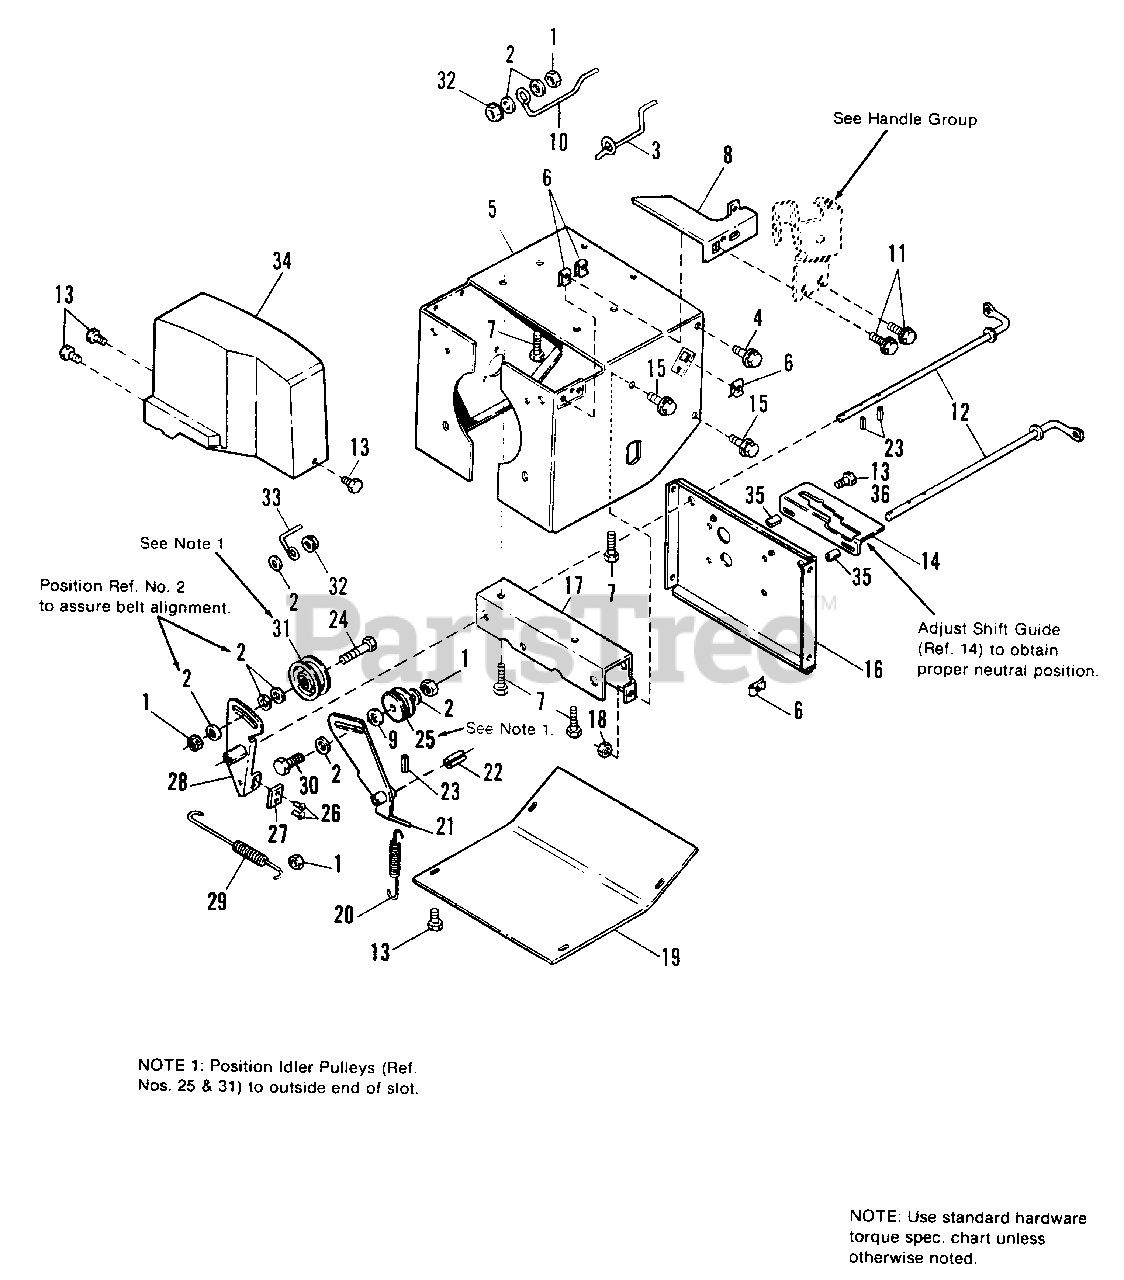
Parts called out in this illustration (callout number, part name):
1	NUT, Hex, Jam 3/8-16
2	WASHER (Qty. 11 on 1691411, 1691413, 1691414 only)
3	BELT GUIDE, L.H. (1691411, 1691413, 1691414 only)
4	SCREW, Hex, Flange, Lock, 5/16-18 x 1-1/4
5	FRAME (1691011, 1691181 only)
5	FRAME (1691411, 1691413, 1691414 only)
6	PALNUT, 5/16-18
7	SCREW, Hex, 5/16-18 x 1-1/2-5 HP Only
8	COVER, Belt
9	SPACER, (1691411, 1691413, 1691014 only)
10	BELT GUIDE, R.H. (1691411, 1695413, 1691414 only)
11	SCREW, Hex, 5/16-18 x 3/4
13	SCREW, Hex, Taptite, 1/4-20 x 1/2 (Qty. 7 on 755)
14	GUIDE, Shift
15	SCREW, Hex., Fl. Lock, 5/16-18 x 3/4
16	MOUNTING PLATE, Trans.
17	SUPPORT, Trans.
18	NUT, Hex, Fl. Lock, 5/16-18
19	PAN, Bottom
21	IDLER ARM ASSY., Traction (5 HP Only)
24	CAPSCREW, Hex, 3/8-16 x 1-3/8 (1691011, 1691181 only)
25	PULLEY, Idler (Incl. Ref. No. 9)
27	PAD, Brake
28	IDLER ARM & BRAKE ASSY. (Incl. Ref. Nos. 26 & 27)
29	SPRING, Brake Return
30	CAPSCREW, Hex, 3/8-16 x 1-1/4
31	PULLEY, Idler, Auger
32	NUT, Hex, Fl. Lock, 3/8-16
33	GUIDE, Belt
34	GUARD, Belt (5 HP Only)
35	SPACER-7 HP Only
36	SCREW, Hex Hd., Taptite 1/4-20 x 1-1/2 (7 HP Only)
